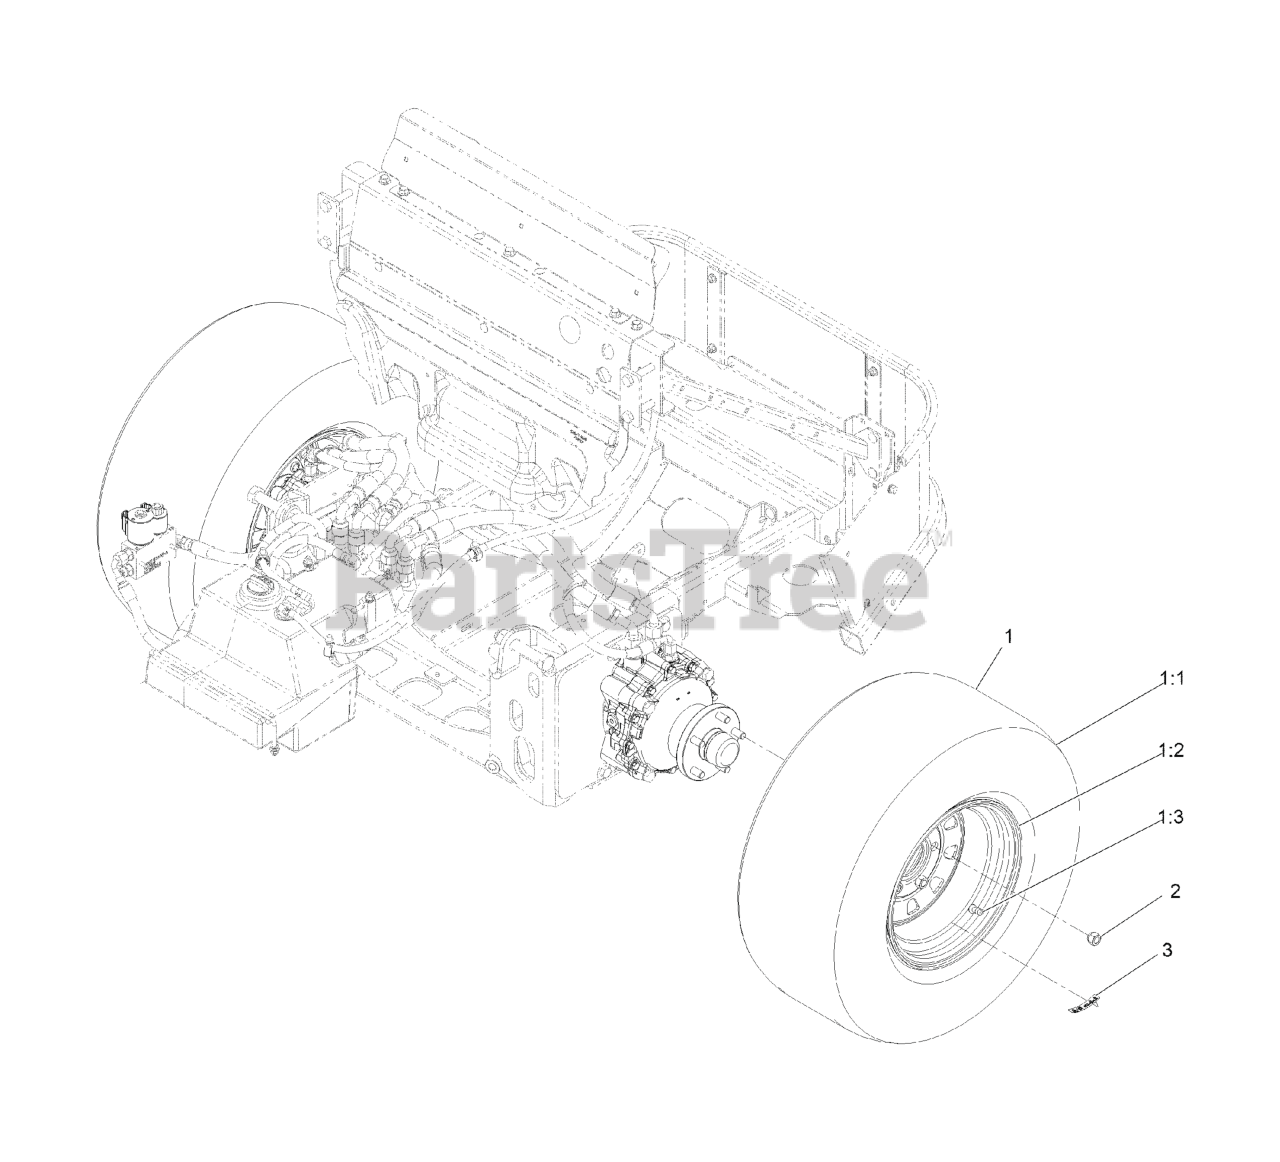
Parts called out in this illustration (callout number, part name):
1	ASM-TIRE 26 X 12-12
1:1	RIM ASM
1:3	Stem-Valve
2	NUT-LUG
3	DECAL-TORQUE, WHEEL NUT
